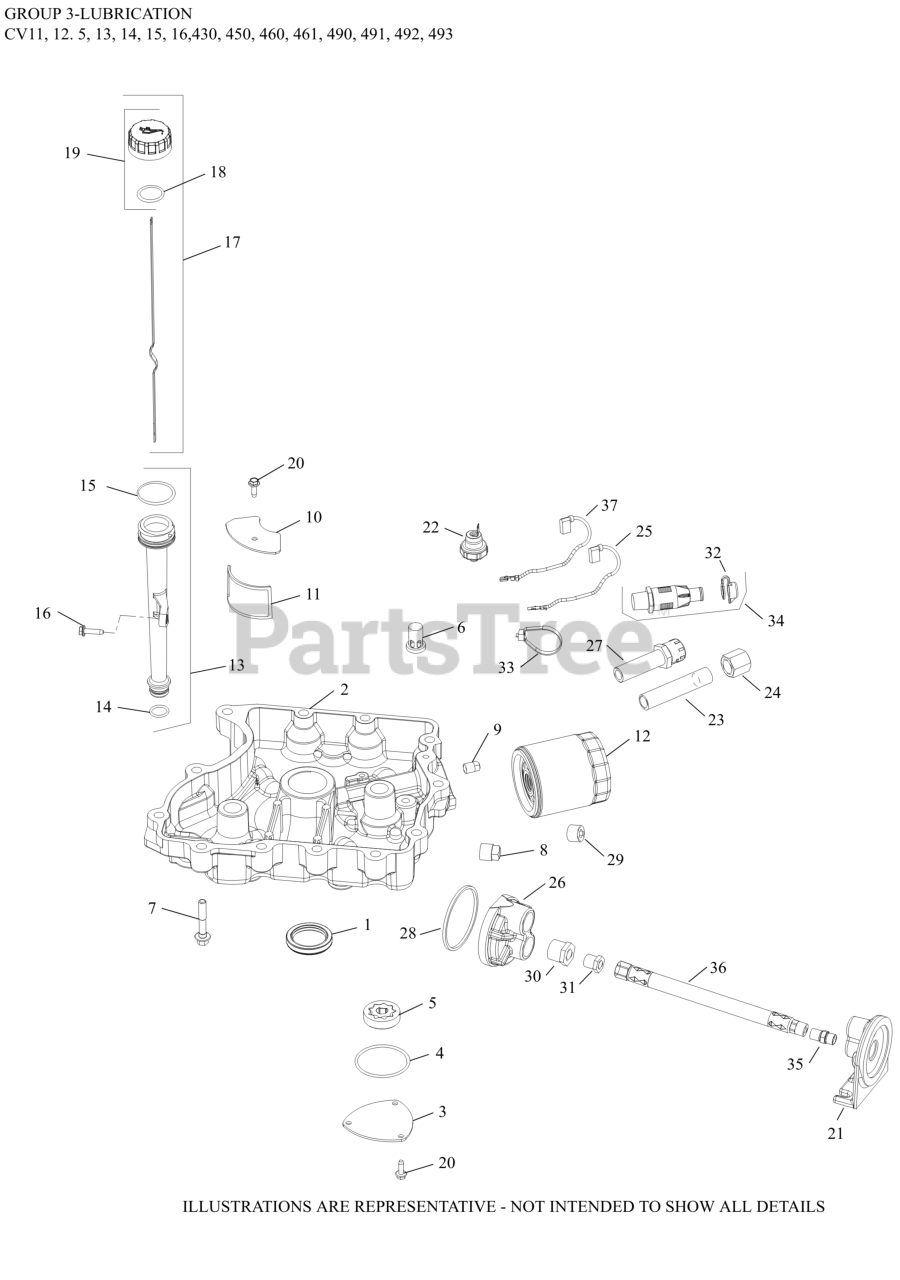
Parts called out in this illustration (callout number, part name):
1	SEAL, OIL
3	COVER, OIL PUMP
4	O-RING (2.5" DIA)
5	PUMP ASSEMBLY, OIL-(#DSC)
6	VALVE, OIL PRESSURE RELIEF
7	SCREW, FLG M8X1.25X45
8	PLUG, SQ HD PIPE 3/8"
9	PLUG, PIPE 1/8 NPTF-SQ.HD.
11	SCREEN, OIL-USE 24 162 26-S
12	OIL FILTER
13	TUBE ASSEMBLY
14	O-RING, LOWER OIL FILL TUBE
15	O-RING, UPPER OIL FILL TUBE
16	SCREW, FLG THD FRM M5X.8X20-(#25086399S)
17	DIPSTICK/CAP ASSY (BLACK)
17	DIPSTICK/CAP ASSY (YELLOW)-(#DSC)
18	O-RING, DIPSTICK
19	KIT, OIL FILL CAP (BLACK)
20	SCREW, THREAD FORMING
20	SCREW,FLG THD FRM M5X0.8X16-(#25086398S)
